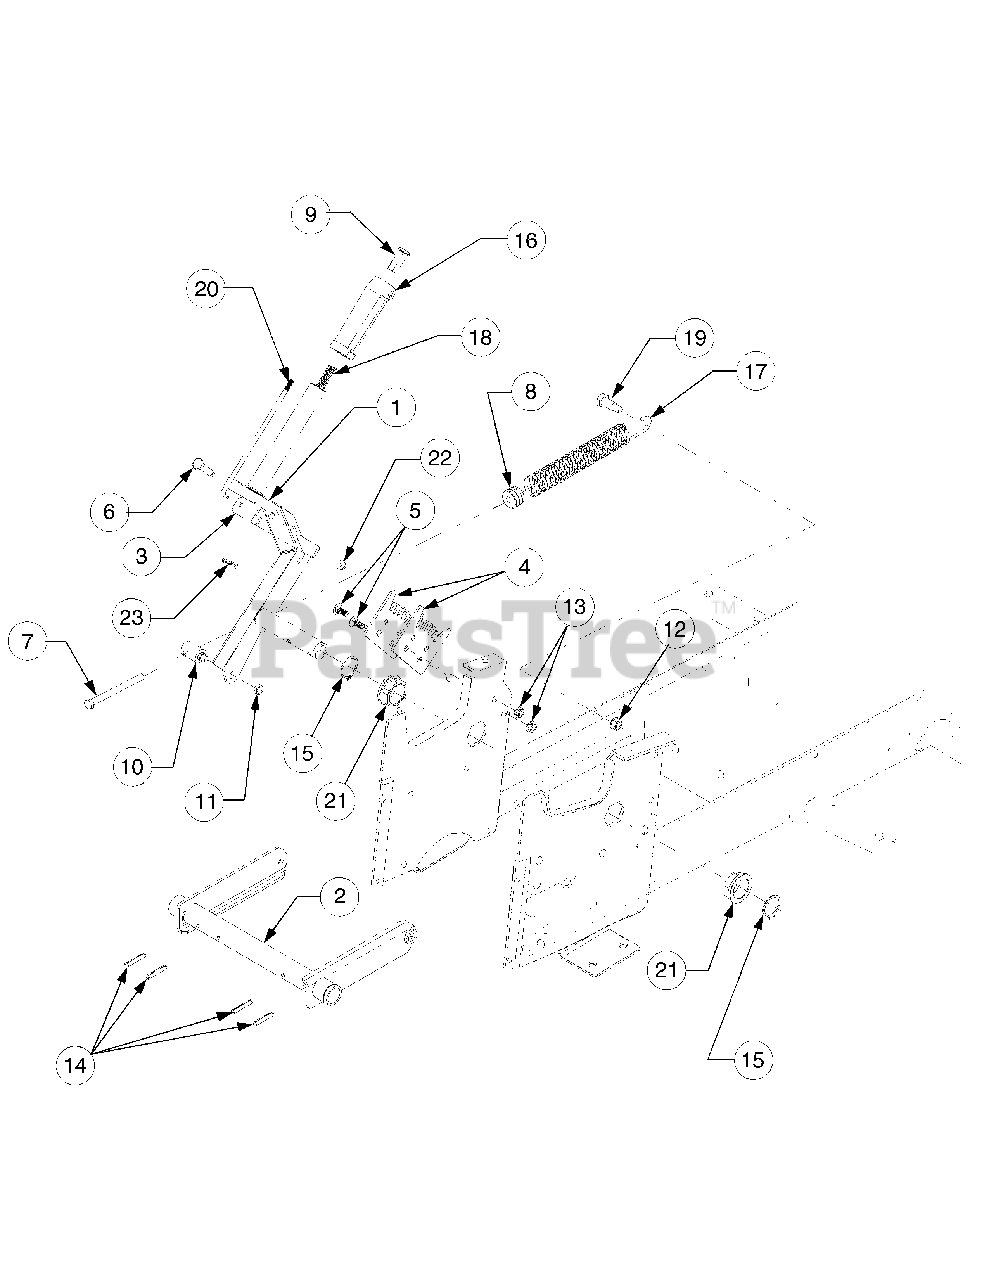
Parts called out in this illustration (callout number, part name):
5	Bolt, Carriage, 5/16-18 x .75
6	Screw, Shoulder, .374 x 1.375
7	Screw, Hex Cap, 3/8-16 x 4.25 GR5
8	Insert, Spring
9	Button, Handle
10	Ferrule, Adjustment
11	Nut, Hex Center Lock, Jam, 3/8-24
12	Nut, Hex Flanged Lock, 3/8-16
12	Nut, Hex Flanged Lock, 3/8-16, GrF
13	Nut, Hex Flanged Top Lock, 5/16-18
14	Pin, Spiral Spring, 1/4 Dia x 1.5
15	Ring, Snap, 1.25 Dia Shaft
16	Grip, Lift Handle
17	Spring, Extension
18	Spring, Compression
19	Bolt, Shoulder
20	Rod, Index
21	Bearing, Hex Flange, 1.25 ID
22	Nut, Hex Flange Lock, 1/4-20
23	Pin, Internal Cotter
